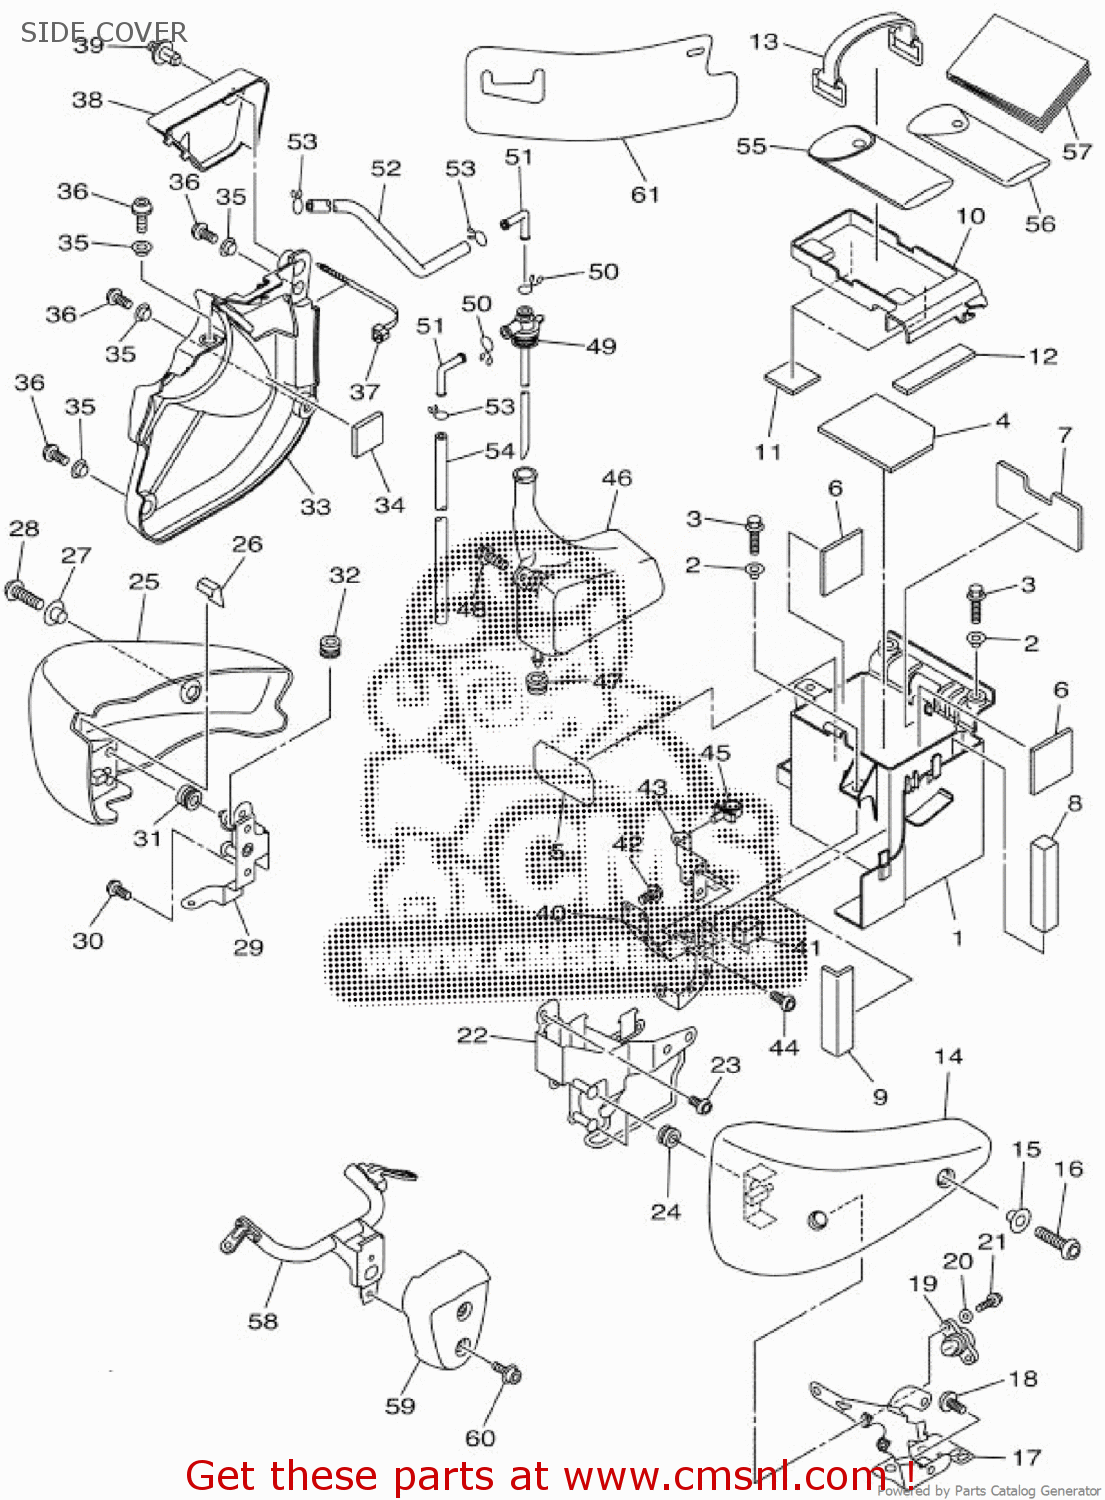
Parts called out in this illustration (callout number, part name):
1	BOX, BATTERY
2	COLLAR
3	BOLT, FLANGE
4	SEAT, BATTERY
5	PROTECTOR
6	DAMPER
7	DAMPER
8	DAMPER, LOCATING 2
9	DAMPER, LOCATING 3
10	BOX, TOOL
11	DAMPER
12	DAMPER (L.H)
13	BAND, BATTERY
14	COVER, SIDE 1
15	COLLAR
16	SCREW
17	BRACKET 1
18	SCREW, TAPPING(3NG)
19	ROTOR SET
20	WASHER, PLATE
21	BOLT, WASHER BASED(3XC)
22	BRACKET 3
23	HEX BOLT 6X12
24	GROMMET(3VD)
25	COVER, SIDE 2
26	PROTECTOR
27	COLLAR
28	BOLT
29	BRACKET 4
30	HEX BOLT 6X12
31	GROMMET(3VD)
32	GROMMET(46X)
33	COVER, SIDE 4
34	DAMPER 1
35	COLLAR
36	BOLT
37	CLAMP(4FM)
38	PLATE
39	RIVET(4PH)
40	BRACKET 1
41	DAMPER, LOCATING 1
42	HEX BOLT 6X12
43	BRACKET 2
44	HEX BOLT 6X12
45	CLAMP
46	TANK, RECOVERY
47	GROMMET(4FU)
48	BOLT, WITH WASHER
49	CAP
50	CLIP, PIPE
51	ELBOW
52	PIPE, BREATHER
53	CLIP 101235600
54	HOSE
55	TOOL KIT
56	TOOL KIT, 2
57	O/M XVS1300A '16
58	STAY, COVER
59	COVER, CARBURETOR 1
60	BOLT, HEXAGON SOCKET HEAD
61	COVER
